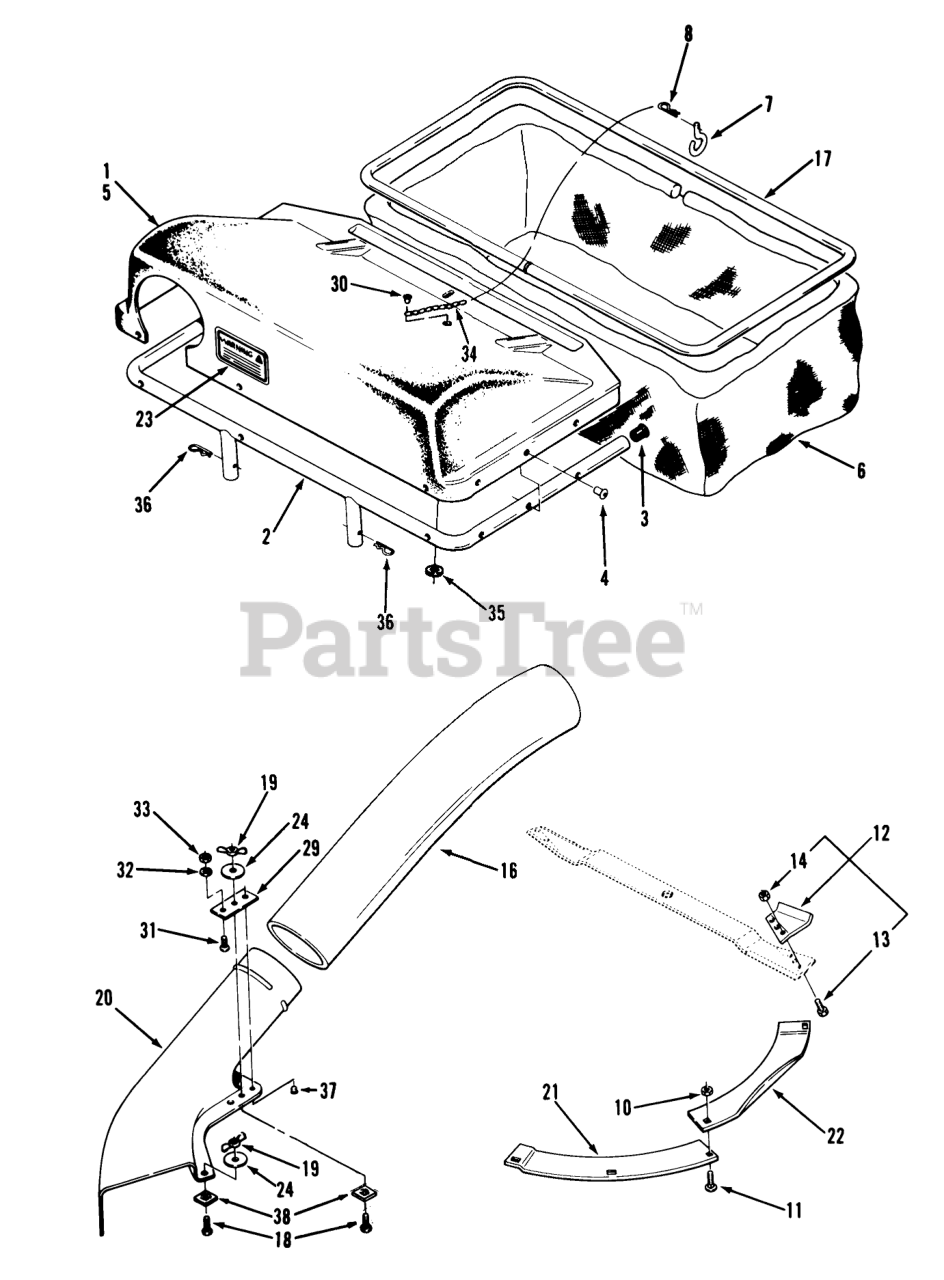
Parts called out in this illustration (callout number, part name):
1	Top Assembly (Includes Items #2-5, 30, 34 & 35)
2	Frame
4	NUT-HEX
5	TOP BAGGER
6	Bag-White
7	LATCH PIN
8	Hairpin Cotter
9	Decal-Danger
10	NUT-HEX
11	BOLT-CARR
12	Lift Tab Kit (Includes 13 & 14)
13	BOLT 5/16-18X5/8
14	NUT-LOCK 5/16-18
16	TUBE COLLECTOR
17	FRAME BAG B
18	SCREW-CARR
19	WING NUT
20	Elbow Assembly (Includes Items 29-33)
21	PLATE MOWER RING B (NS)
22	PLATE MOWER B
23	DECAL-WARNING
24	WASHER
29	PLATE
30	RIVET
31	Screw
32	WASHER-LOCK
33	NUT-HEX
34	CHAIN MAKE FRM111098
35	Washer
36	Pin-Cotter
37	RIVET -4
38	SPEED NUT 1/4-20
